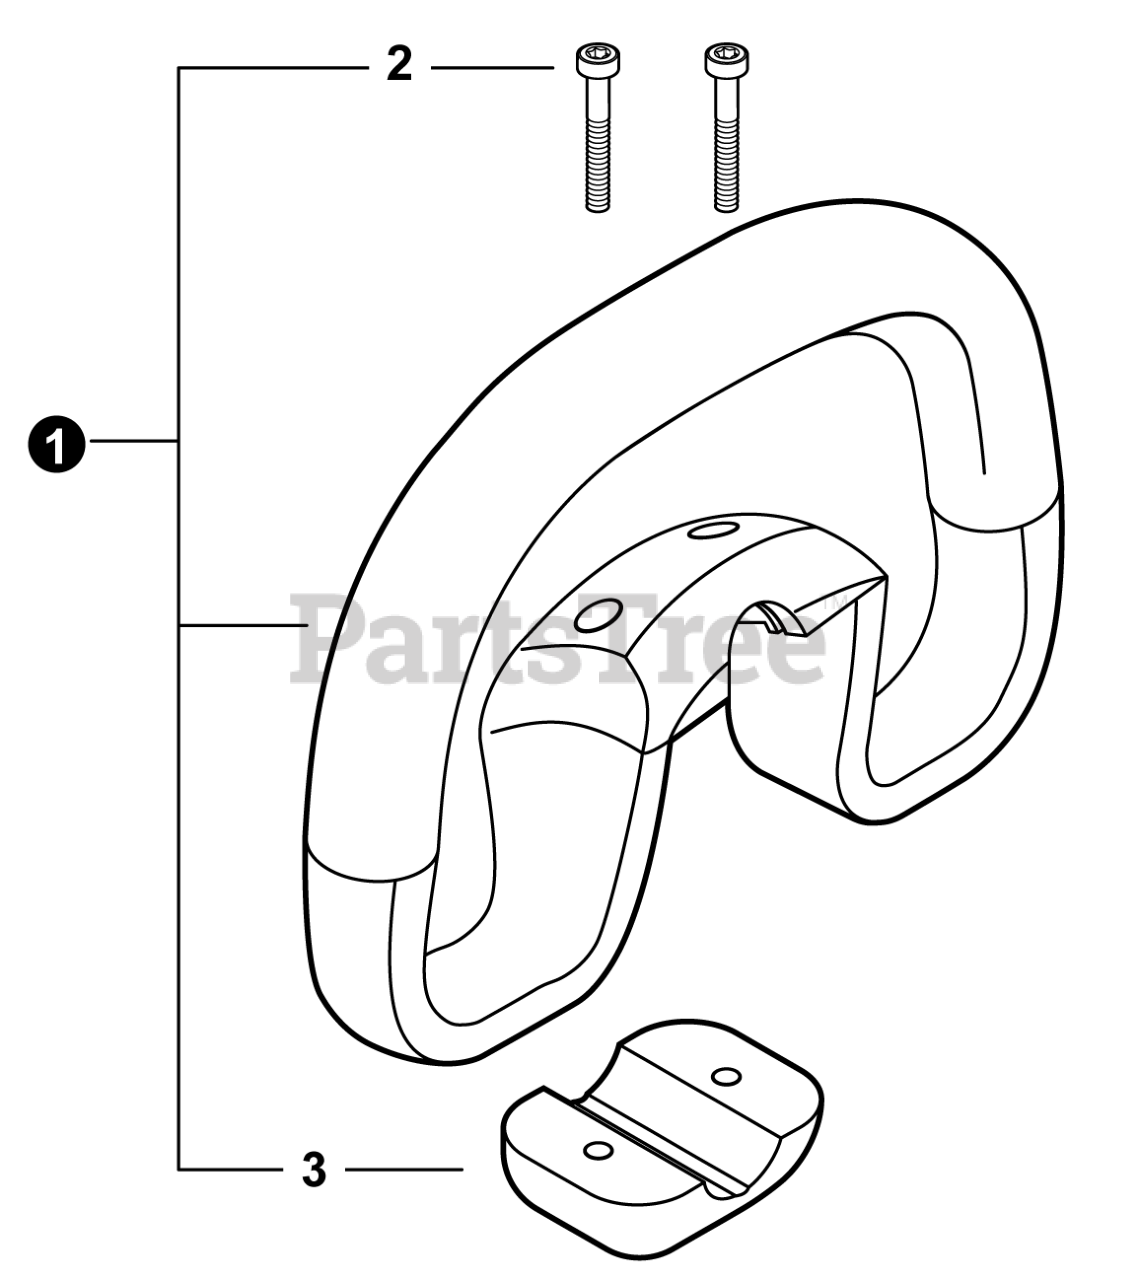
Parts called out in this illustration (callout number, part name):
1	HANDLE ASSY - SUPPORT
2	BOLT, TORX 5x35
3	BRACKET, HANDLE
